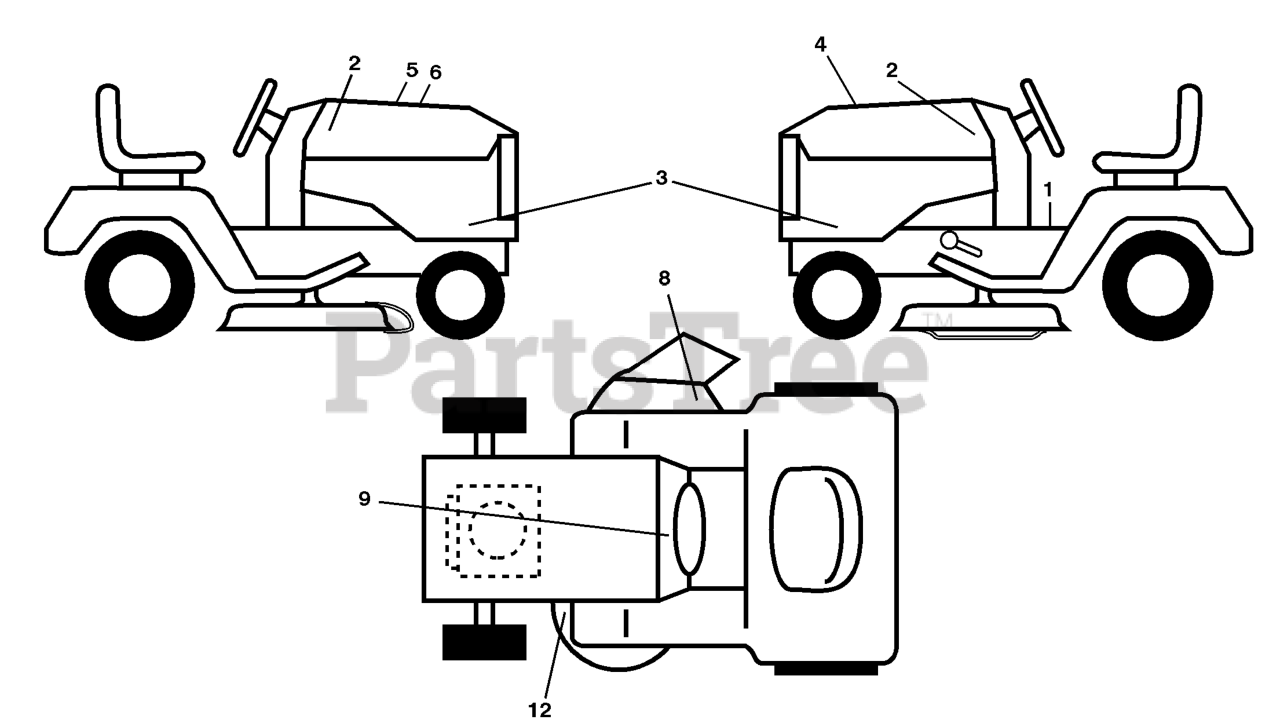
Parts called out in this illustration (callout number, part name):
1	DECAL.FENDER.WARNING.ENG
2	EMBLEM.HOOD.HUSQ.DEALER
3	DECAL.SDPNL.2246LS.ENDUR.HUSQV
4	DECAL.ENG.BSM40.ENDUR.278169
5	DECAL HOOD CUST. RESP.
6	DECAL.REPLACEMENT.2246LS.2008
8	DECAL.REPLACEMENT.2246LS.2008
9	DECAL BTRY SYMBOLS
12	DECAL V BELT SCHEMATIC
